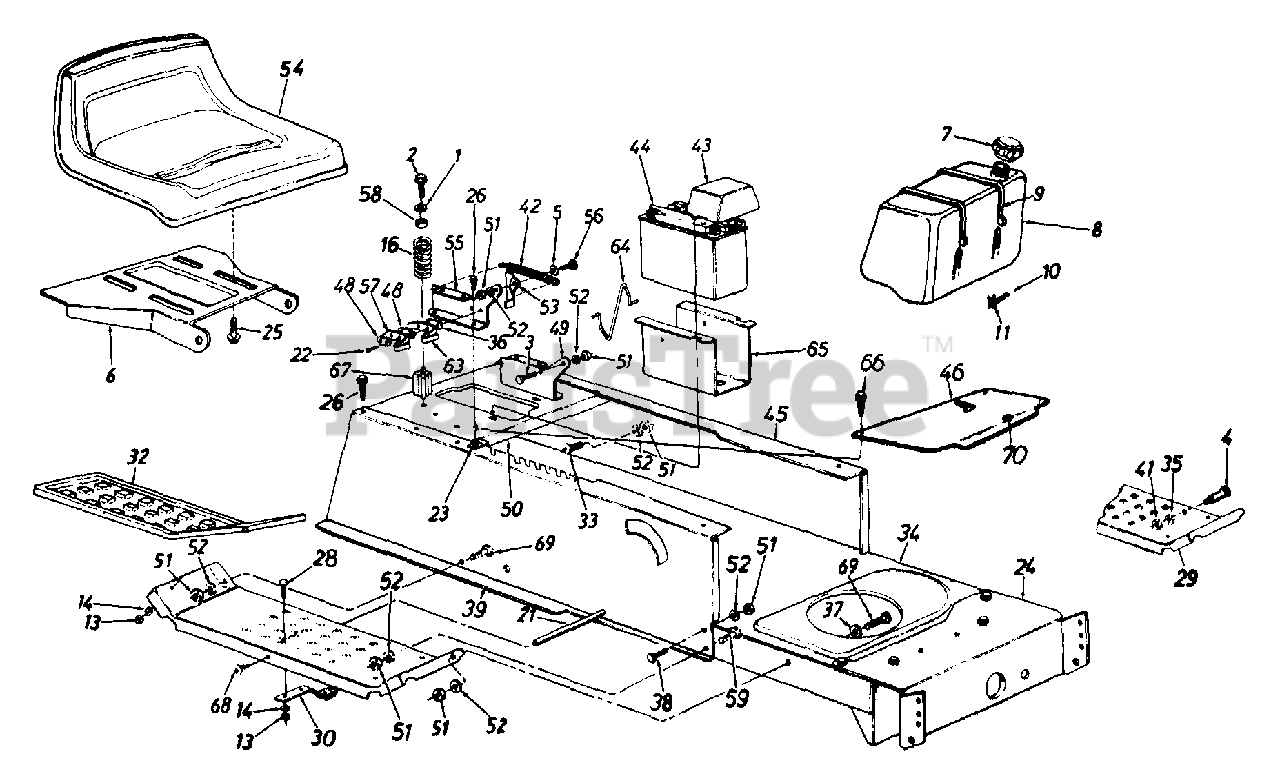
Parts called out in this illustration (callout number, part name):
1	Fl-Wash. .344" I.D. x .875"
2	Hex Wash. Hd. Tap Scr. 5/16-18 x 3.25" Lg.
3	Shld. Bolt .437" Dia. x .162"
4	Shld. Bolt .50" Dia. x .84"
5	Spr-Wash. .445" I.D. x .75
7	Fuel Cap
8	Fuel Tank
9	Tie Strap
10	Fuel Line
11	Hose Clamp
13	Hex Nut 1/4-20 Thd.
14	L-Wash. 1/4" I.D.
16	Compression Spring
21	Running Board Rod
23	Speed Nut #10Z
24	Front Pivot Brkt.
25	Hex Tap Scr. 3/8-16 x .75"
26	Hex Wash. Hd. AB-Tap Scr. 5/16 x .75" Lg.
28	Carriage Bolt 1/4-20 x .62"
29	Running Board (R.H. & L.H.)
30	Blade Brake Ass'y.
32	Rubber Foot Pad - L.H.
33	Truss Mach. Scr. 5/16-18 x .75" Lg.
34	Lower Frame
35	L-Wash. 3/8" I.D.
36	Insulator Boss Plate
37	Fl-Wash. .344" I.D. x .625" O.D.
38	Hex Bolt 5/16-18 x .75" Lg.
42	Extension Spring 5.31" Lg.
43	Battery Cover
44	12-V Battery
45	Upper Frame - L.H.
46	Shift Cover
48	Insulator Plate
52	L-Wash. 5/16" I.D.
53	Seat Lift Brkt.
54	Seat 8-7/8" High
56	Shld. Bolt .437" Dia. x .268"
57	Spring Switch
58	Bushing
59	Hex Wash. TT-Tap Scr. 5/16-18 x 7/8" Lg.
63	Safety Switch (Seat)
64	Battery Tray Clip
65	Battery Tray
66	Truss Mach. B-Tap Scr. #10 x .5" Lg.
67	Spring Spacer
68	Pan Hd. Cutting Scr. 5/16-18 x .75" Lg.
69	Hex Bolt 5/16-18 x .75" Lg.
70	Snap Bushing
17622C-0637	FRAME-UPPER RH SID - POWDER BLACK (0637)
17622C-0638	FRAME-UPPER RH SID - MTD/TROY-BILT RED (0638)
